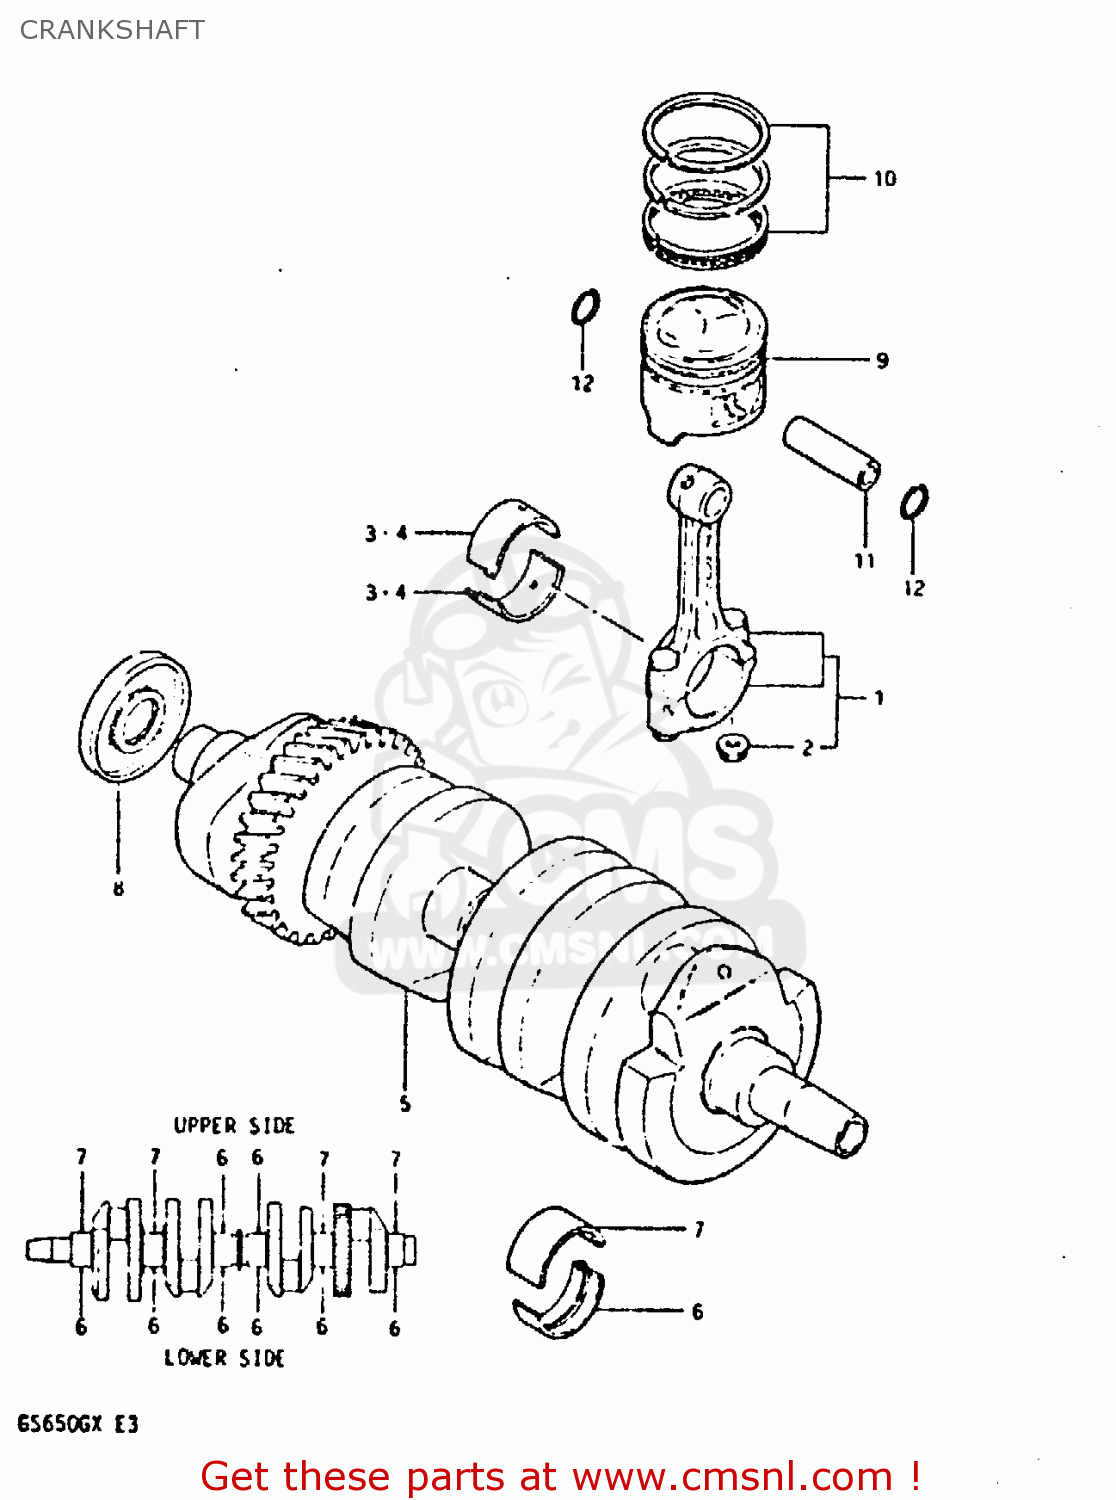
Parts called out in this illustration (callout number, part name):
1	ROD ASSEMBLY,CONNECTING
2	NUT
3	BEARING,CRANK PIN
4	BEARING,CRANK PIN
5	CRANKSHAFT
6	METAL CRANKSHAFT
7	METAL CRANKSHAFT
8	OIL SEAL
9	PISTON
10	RING SET,PISTON
11	PIN,PISTON
12	CIRCLIP
